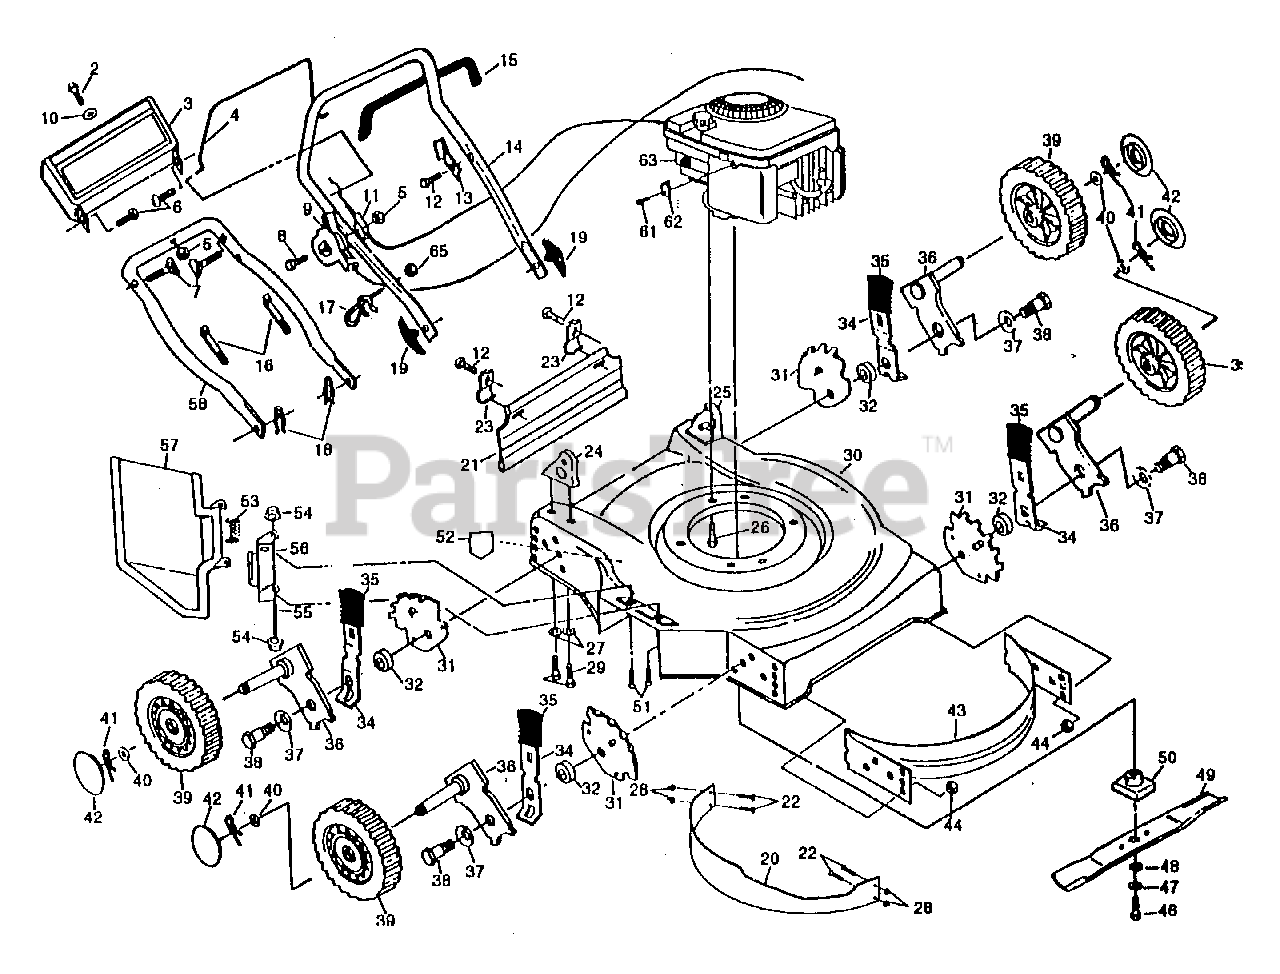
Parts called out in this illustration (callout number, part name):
2	Hex Washer Head Screw 1/4-20 x 1-1/2
3	Trim Plate
4	Control Bar
5	Locknut 1/4-20
6	Self-tapping Screw #10-24 x 5/8
7	Handle Bolt 5/16-18 x 1-3/4
8	Hex Washer Head Screw 1/4-20 x 2.12
9	Throttle Control
11	Engine Zone Control Cable
12	Hex Washer Head Screw 1110-2
13	Up-Stop Bracket
14	Upper Handle
15	Handle Grip
16	Wire Tie
17	Rope Guide
18	Hairpin Cotter
19	Handle Knob
20	Closeout Plate
21	Rear Skirt
22	Machine Screw
23	Rear Skirt Bracket
24	Handle Bracket Assembly (Right)
25	Handle Bracket Assembly (Left)
26	Thread Rolling Screw 3/8-16 x 1
29	Screw 5/16-18
30	Lawn Mower Housing
31	Wheel Adjusting Bracket
32	Spacer
34	Selector Spring
35	Selector Knob
36	Axle Arm Assembly
37	Belleville Washer
38	Shoulder Bolt 3/8-16
39	Wheel Assembly
41	Retainer Clip
43	Front Baffle
44	Locknut 3/8-16
46	Hex Head Screw 3/8-24 R 1-3/8 Or. 8
47	Helical Lockwasher 3/8
48	Hardened Washer
50	Blade Adapter
51	Screw
52	Danger Decal
53	Torsion Spring
55	Hinge Rod
56	Housing Bracket
57	Discharge Guard
58	Lower Handle
61	Thread Rolling Screw #10-32 x 5/8
62	Cable Clamp
65	Keps Locknut 1/4-20
